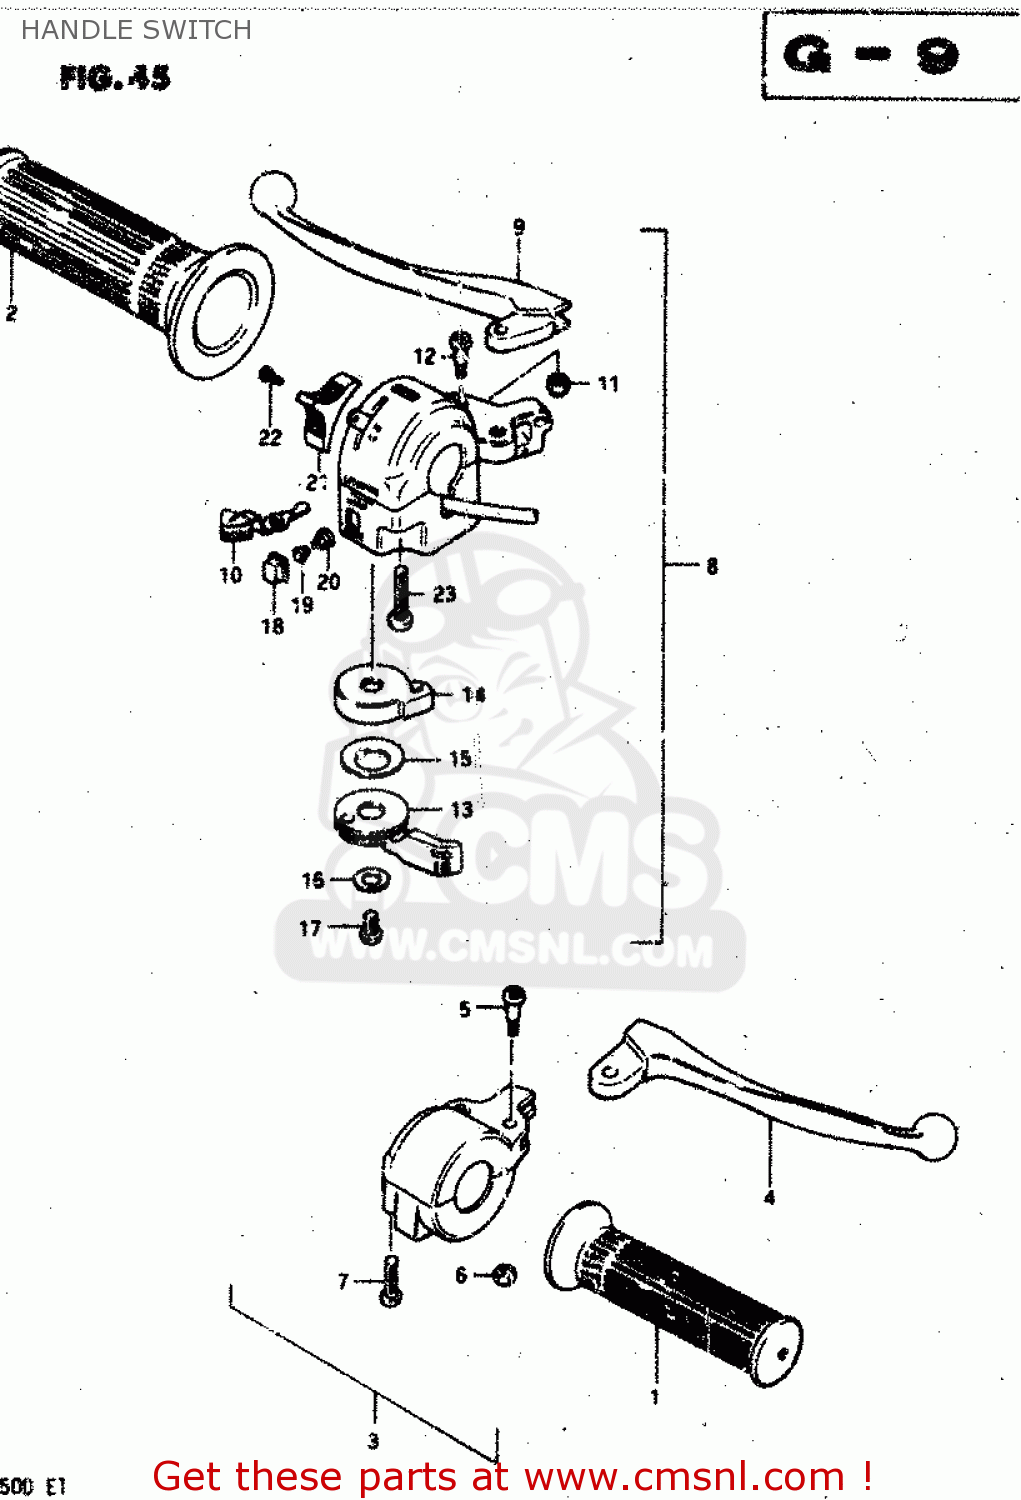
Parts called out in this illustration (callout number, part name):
1	GRIP,THROTTLE
2	GRIP,L
3	BRAKE LEVER & SWITCH ASSY
4	LEVER
5	BOLT,LEVER
6	NUT,LEVER BOLT
7	SCREW
8	CLUTCH LEVER & SWITCH ASSY
9	LEVER
10	KNOB,TURN SIGNAL SWITCH
11	NUT,LEVER BOLT
12	BOLT,LEVER
13	LEVER,STARTER
14	BODY,STARTER LEVER
15	WASHER,ADJUSTER
16	WASHER
17	SCREW
18	BUTTON,HORN
19	CONTACT
20	SPRING
21	KNOB
22	SCREW 3X6
23	SCREW 5X20
